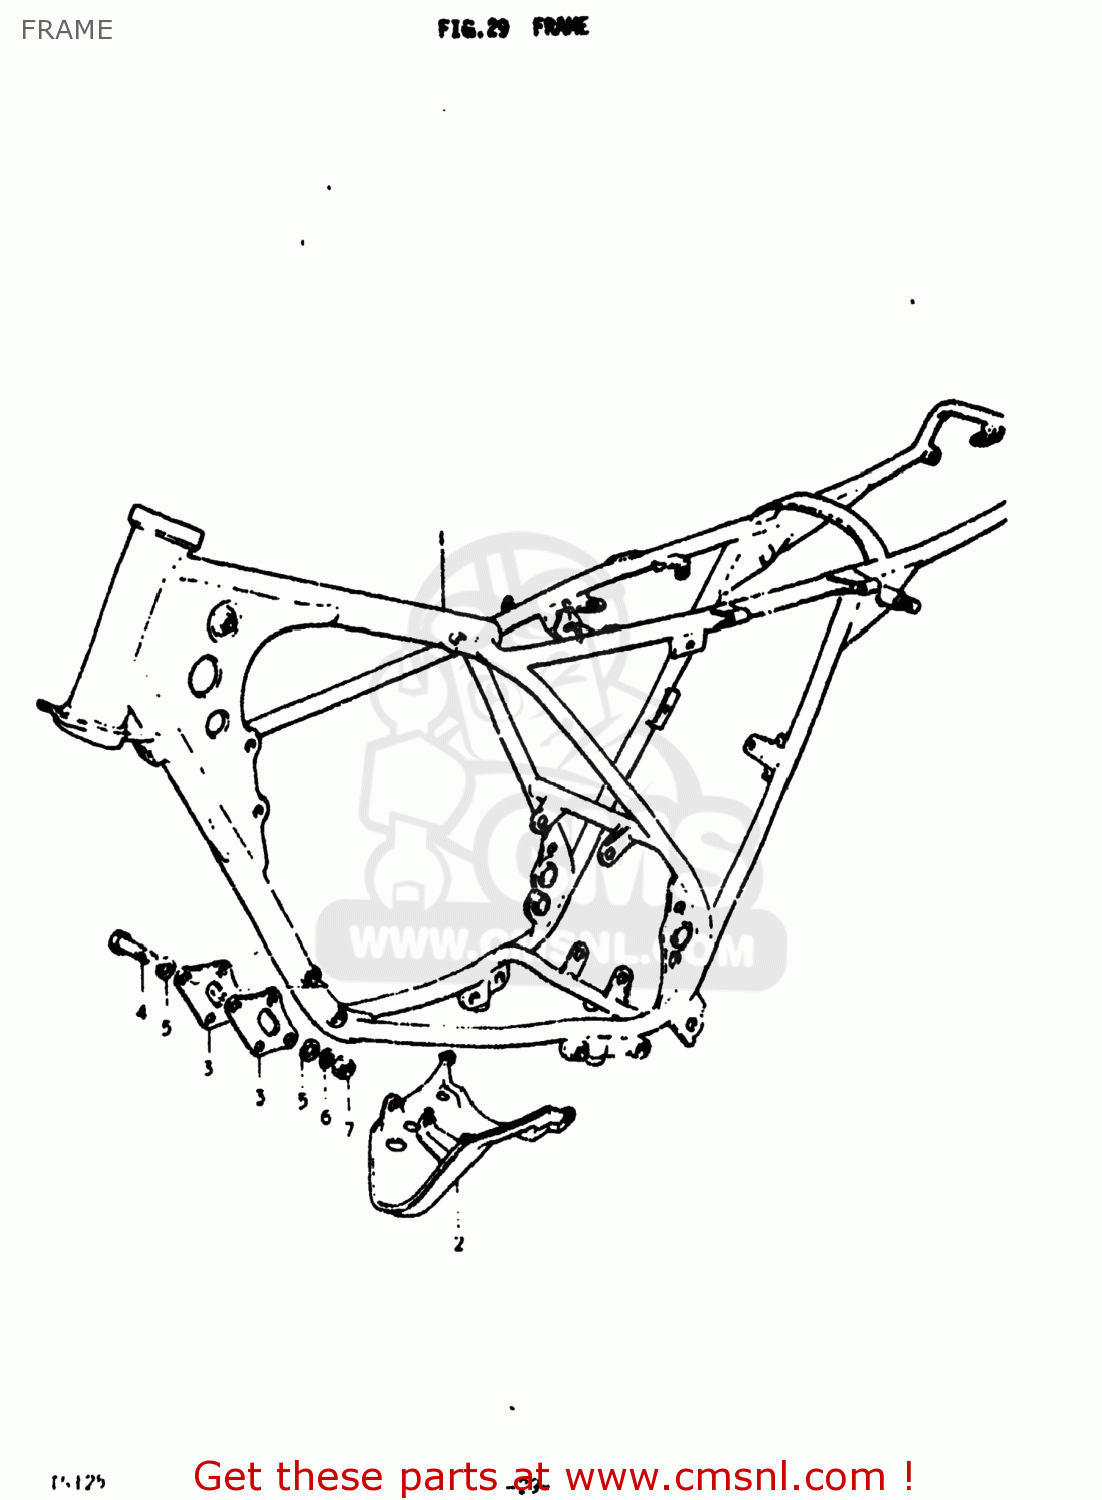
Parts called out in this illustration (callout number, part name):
1	FRAME
2	GROMMET
3	PLATE,ENGINE MOUNTING
4	BOLT
5	WASHER
6	LOCK WASHER
7	NUT
